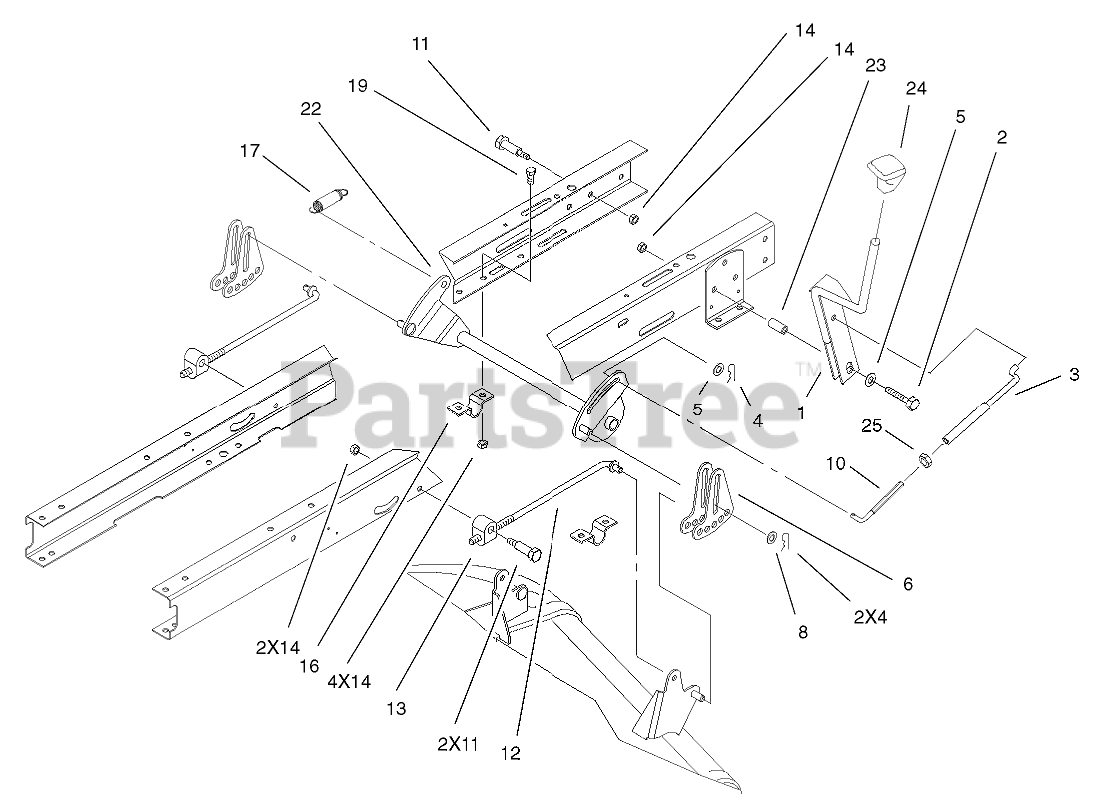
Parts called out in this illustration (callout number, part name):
1	HOC LEVER ASM
2	SCREW-HH
4	PIN-COTTER
5	WASHER-FLAT
6	LINK-ADJUSTING, HOC
8	WASHER-HARDENED
10	LINK-HOC
11	SCREW-SHOULDER, HH
12	ROD-HANGER, REAR
13	TRUNNION-HOC
14	NUT-LOCK, NI
16	CLAMP-PIVOT, HOC
17	SPRING-EXTENSION
19	SCREW-HH
22	PIVOT-HOC
23	SPACER
24	KNOB-SHIFT
25	NUT-JAM
